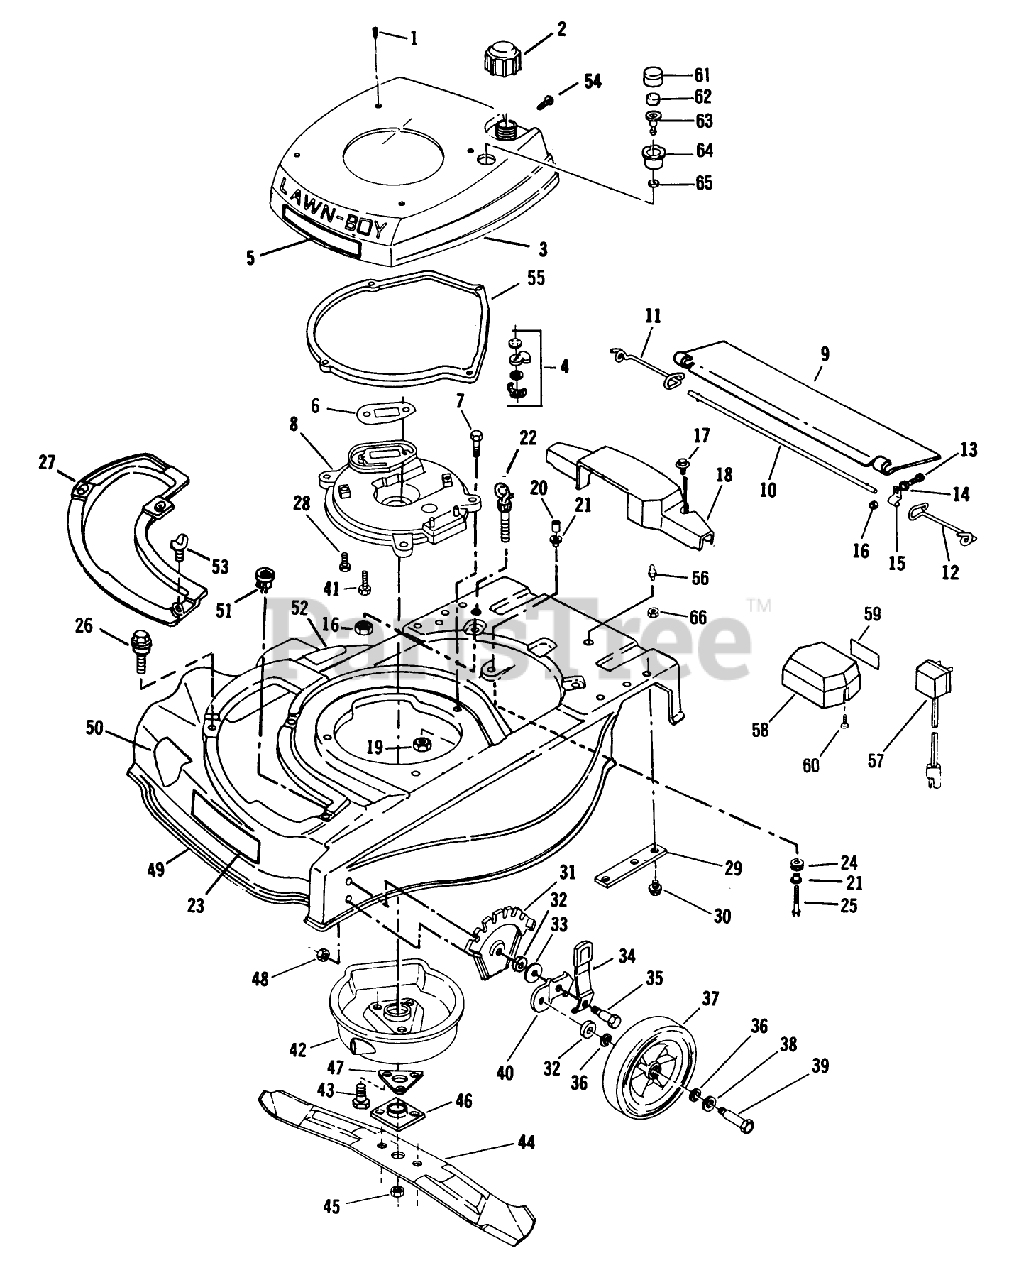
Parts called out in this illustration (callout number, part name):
1	SCREW LAWRENCE
2	FUEL CAP & INSERT
7	SCREW-HH
8	PLATE,MUFFLER F
10	ROD T/SHIELD ADV WIRE
11	SPRING;TRAILING SHIELD RH
12	SPRIG T/SHLD ASOC
14	Washer-Trailing Shield
15	CLAMP ROD KMC
16	LOCKNUT E
17	SCREW SEMS TRM HEX HD
19	NUT-LOCK F
20	SPACER
21	SPACER ECK PRES
22	BOLT-EYE
30	SCREW
31	PLATE HGT ADJ TRO
32	WASHER WROUGHT
33	WASHER
34	KNOB & SPRING
35	BOLT
36	WASHER
37	WHEEL & TIRE KIT
38	SPACER
39	BOLT WHEEL
41	SCREW V
43	SCREW
45	NUT-BLADE
46	PLATE AND COLLAR ASM
47	SUPPORT F
48	LOCKNUT
53	WING SCREW LAWRE
54	SCREW S
62	FILTER S
63	BASE P'MERBULB S
64	CUP PRIMER PL
